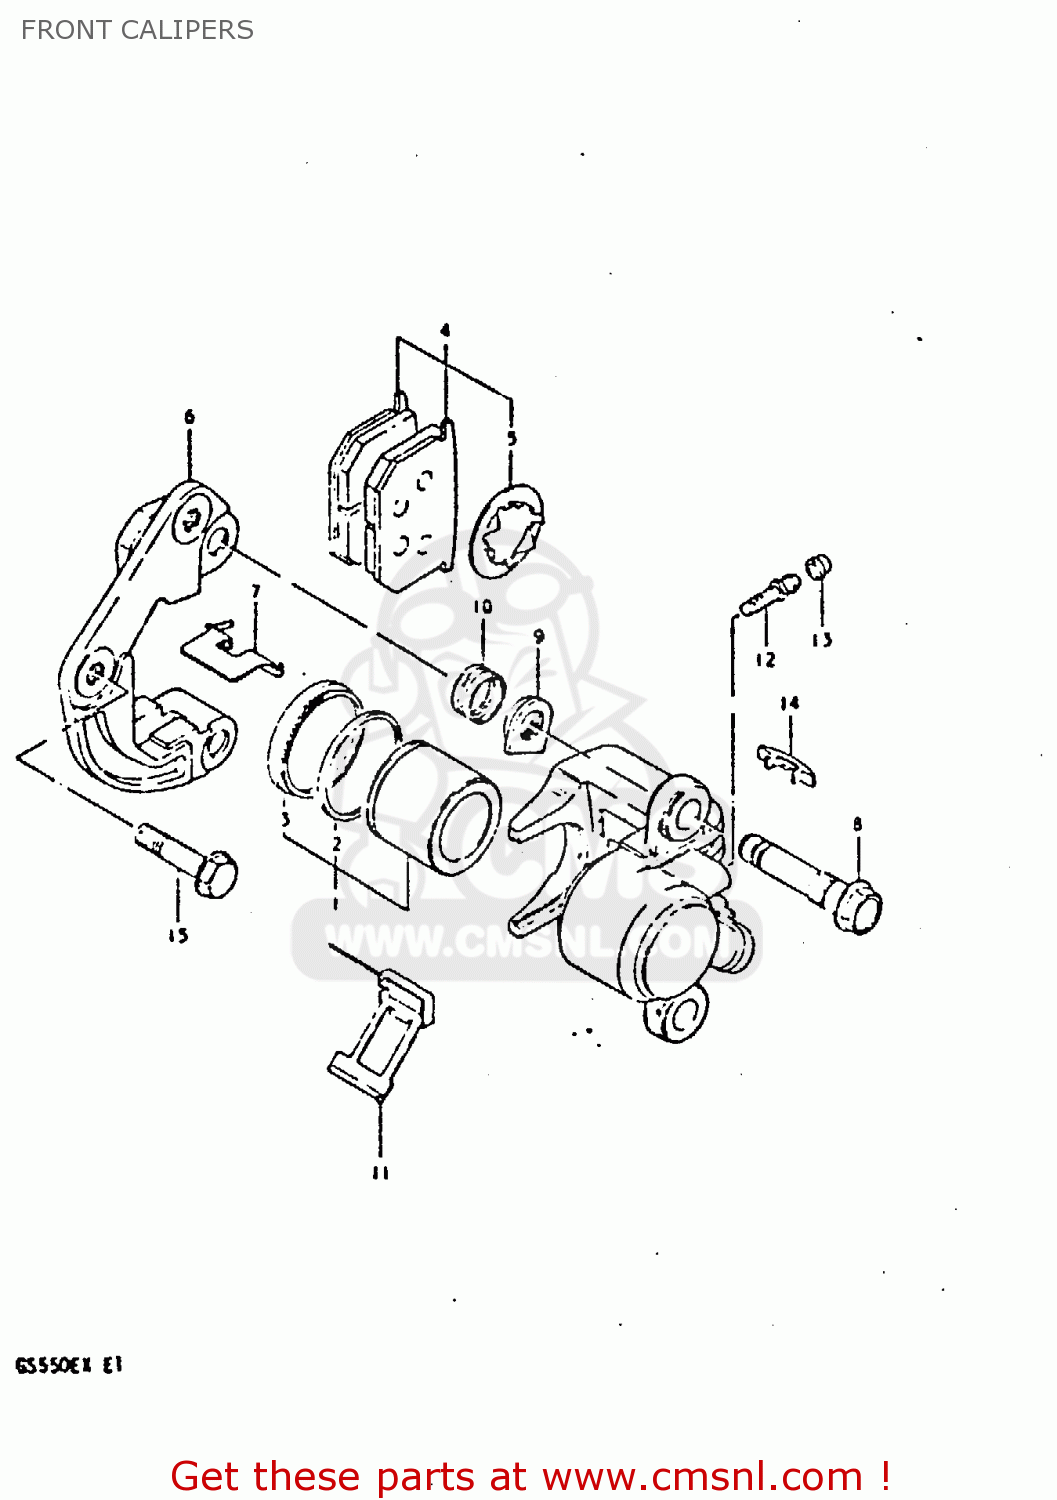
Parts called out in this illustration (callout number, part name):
1	PISTON SET
2	SEAL,PISTON
3	BOOT,PISTON
4	PAD & SHIM SET (MCA)
5	SHIM,PAD
6	HOLDER,CALIPER,LEFT
7	GUIDE,PAD
8	AXLE,CALIPER
9	NUT,CALIPER AXLE
10	BOOT
11	SPRING
12	BREATHER
13	CAP,BLEEDER PL
14	COVER,INDICATOR
15	BOLT(10X37)
